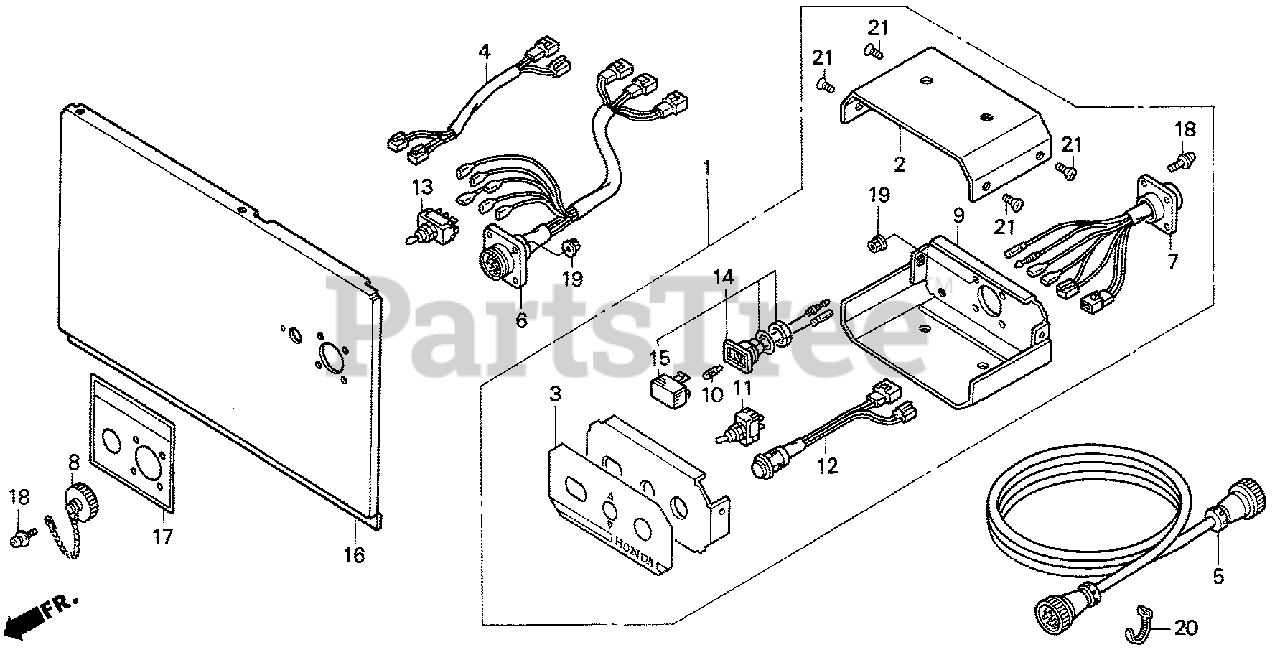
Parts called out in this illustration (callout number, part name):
1	BOX ASSY., REMOTE CONTROL *R8* (BRIGHT RED)
2	COVER (UPPER) *R8*
3	PLATE, SWITCH & INDICATOR
4	SUB-WIRE HARNESS ASSY.
5	CABLE, REMOTE CONTROL (15M)
6	CONNECTOR ASSY., MAIN
7	CONNECTOR ASSY., BOX
8	COVER, CONNECTOR
9	CASE, SWITCH
10	BULB, WEDGE BASE (12V/2W) (TSD30) (STANLEY)
11	SWITCH ASSY., MAIN
12	SWITCH ASSY., STARTER
13	SWITCH ASSY., SELECT
14	SOCKET ASSY., LAMP (GREEN)
15	LENS (GREEN)
16	COVER, GENERATOR MAINTENANCE *B132*
17	MARK, REMOTE CONTROL (E)
18	SCREW-WASHER (3X12)
19	NUT, FLANGE (3MM)
20	TIE, CABLE
21	SCREW, FLAT (4X8)
